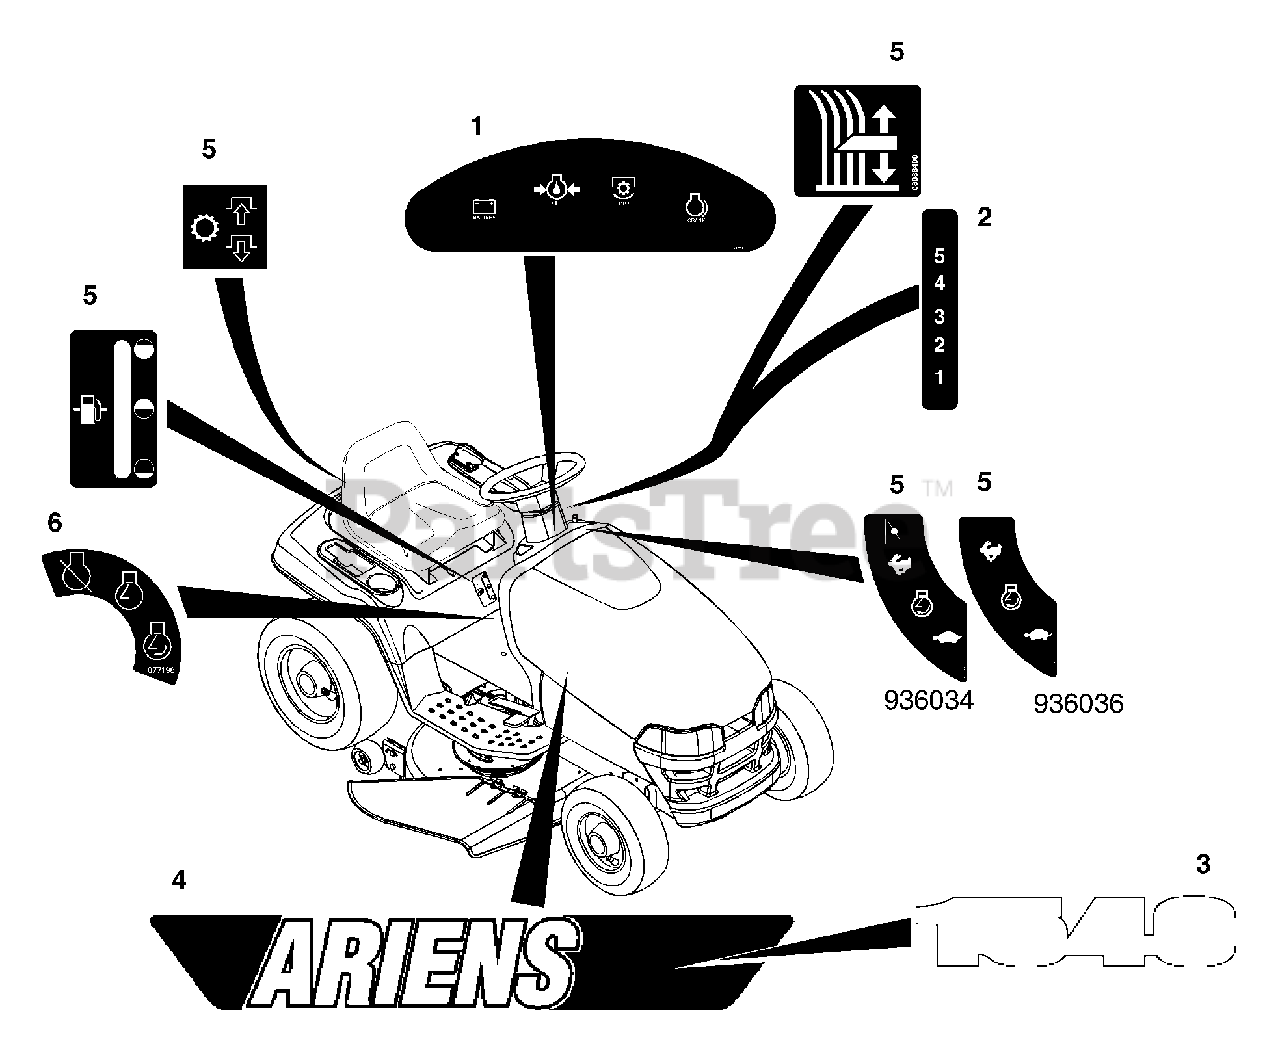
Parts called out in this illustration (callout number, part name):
1	DECAL - DASH W/LIGHTS
2	DECAL, INDICATOR
3	DECAL, HOOD (1540)
4	DECAL-HOOD YT ARIENS
5	SET-YT CONTROLS
6	DECAL - IGNITION
